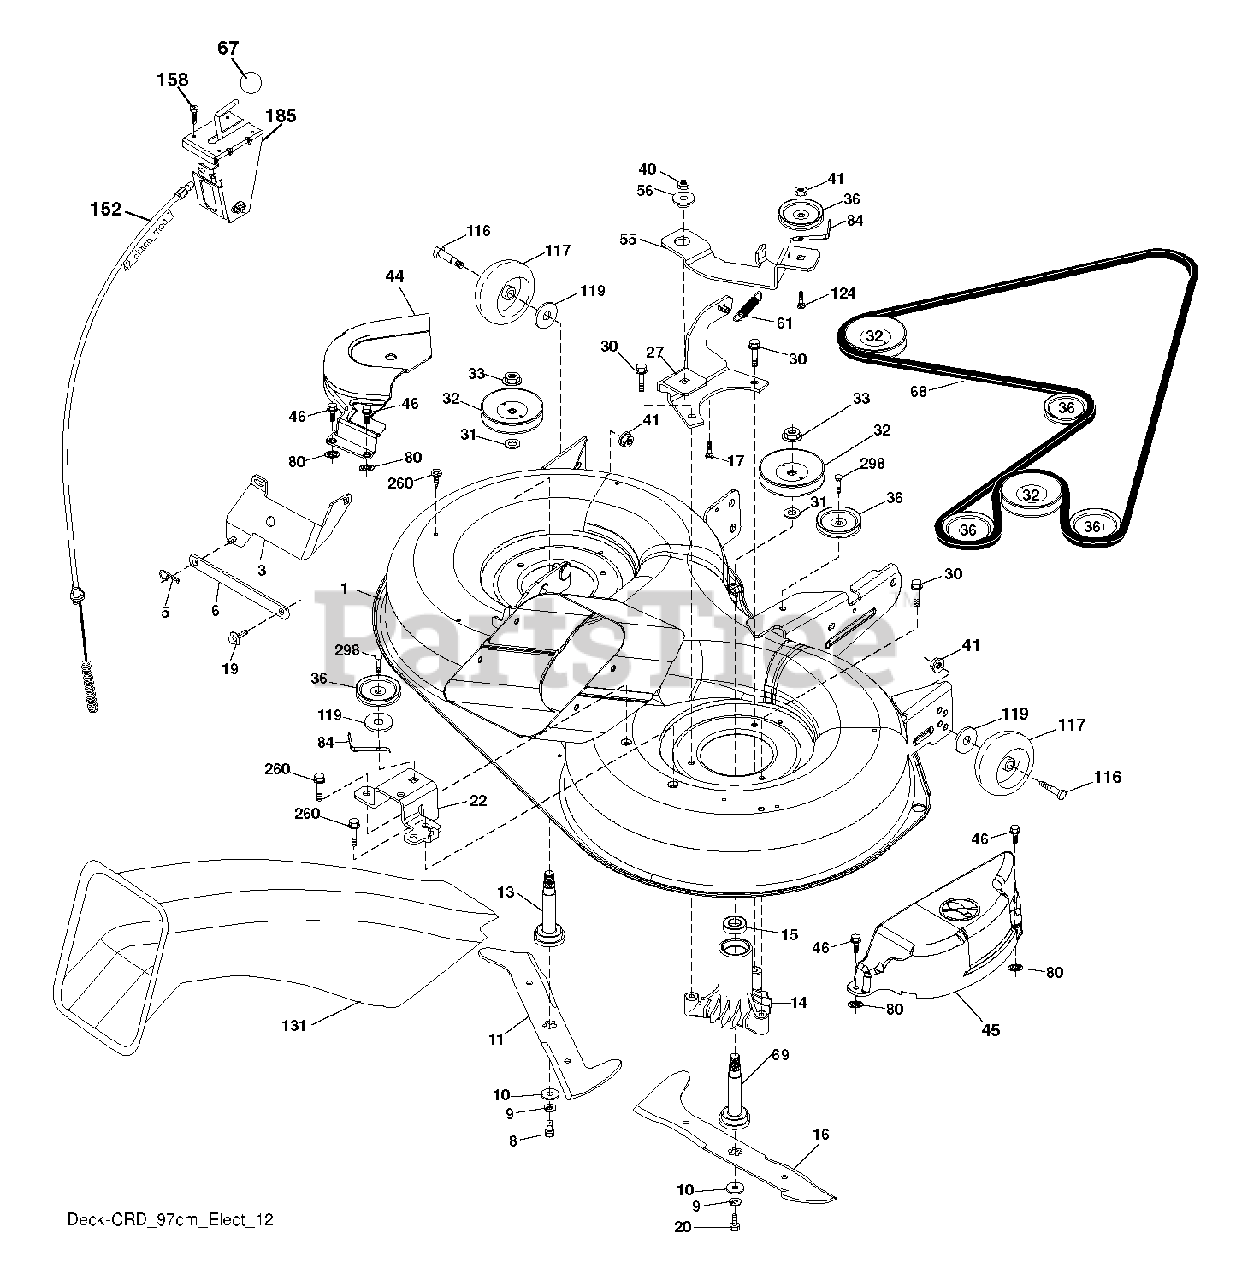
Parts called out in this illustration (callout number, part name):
1	DECK.WLDT.97.CRD.2GWB.
3	BRACKET.ASM.BAR.SWAY.CHASS
5	Retainer Spring
6	BAR.SWAY.92.CRD
8	BOLT.3/8-24X1.25 GR8
9	LOCKWASHER
10	WASHER.BLADE
11	BLADE.3N1.LH.CRD.97
13	SHAFT ASM VENT
14	HOUSING.MANDREL.VENTED (MACHD)
16	BLADE.3N1.RH.CRD.97
17	BOLT.3/8-14X1.25
19	BOLT SHD 5/16-18
20	BOLT.3/8-24X1.25GR8. LHTHRD
22	BRACKET.SUPT.IDLER.REAR.RH
27	BRACKET.ASM.SUSP.REAR.RH.
30	SCREW, WASHER HEAD
31	WASHER.SPACER.MANDREL
32	PULLEY MANDREL
33	NUT.FLANGE.LOCK.TOP
36	PULLEY.IDLER.4.25
41	NUT LOCK FLG 3/8-16 UNC
44	OVER.MANDREL.LH.CRD
45	97.CRD.RH.MANDREL.COVER
46	SCREW.1/4-20X5/8
55	ARM.IDLER.92 CRD.2006
56	SPACER.RETAINER.MOWER
61	SPRING
67	KNOB T (3/8 HOLE)
68	BELT.DRIVE.CRD.97.2010
69	SHAFT.ASM.W/LWR.BRG.RH.THREAD
84	KEEPER, BELT IDLER
116	BOLT.SHOULDER.3/8-16X3-5/8.
117	WHEEL. GUAGE RALLY
119	WASHER
124	BOLT.3/8-16X1.50
131	CHUTE BAGGER
158	SCREW
185	HEAD ASM. CABLE CLUTCH
260	SCREW 3/8-16X1/2
298	SCREW LT
